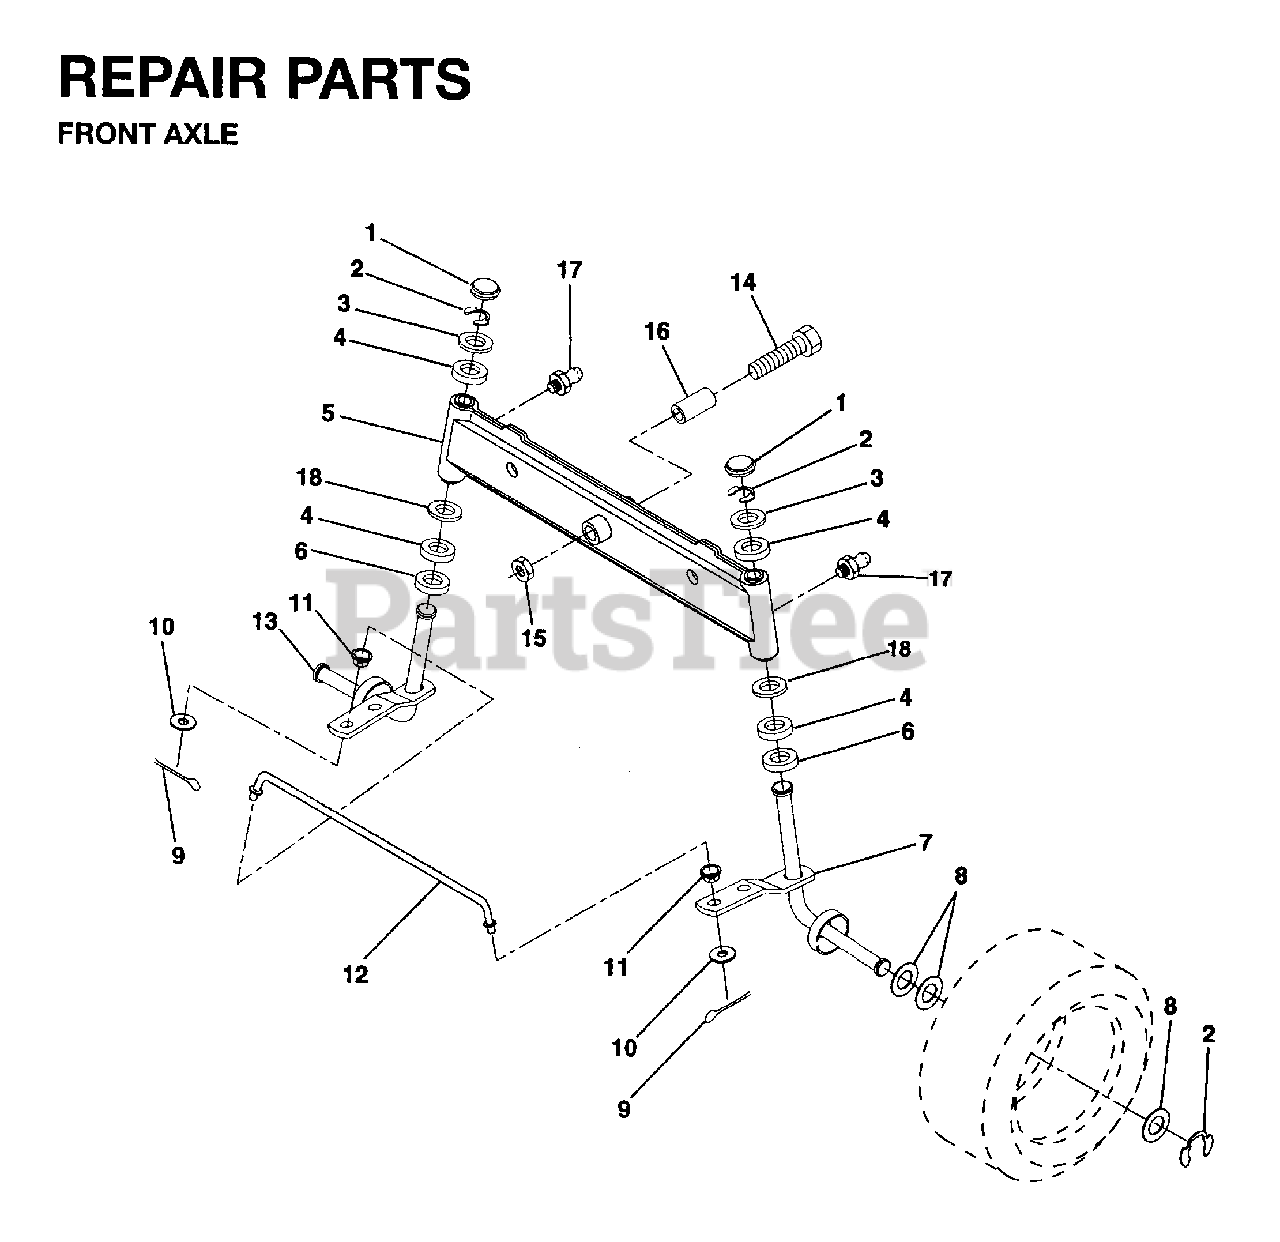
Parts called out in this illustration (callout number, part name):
1	CAP.SPINDLE
2	RING CLIP
4	BEARING.STEERING.COLUMN
5	AXLE ASSY
6	WASHER THRUST
7	SPINDLE ASSY RH NLA
9	COTTER PIN
10	WASHER
11	BUSHING.DRAGLINK
12	TIE ROD
13	SPINDLE ASSY LH
14	BOLT.HEX.5/8-11
15	LOCKNUT
16	BEARING
17	ZERK M
